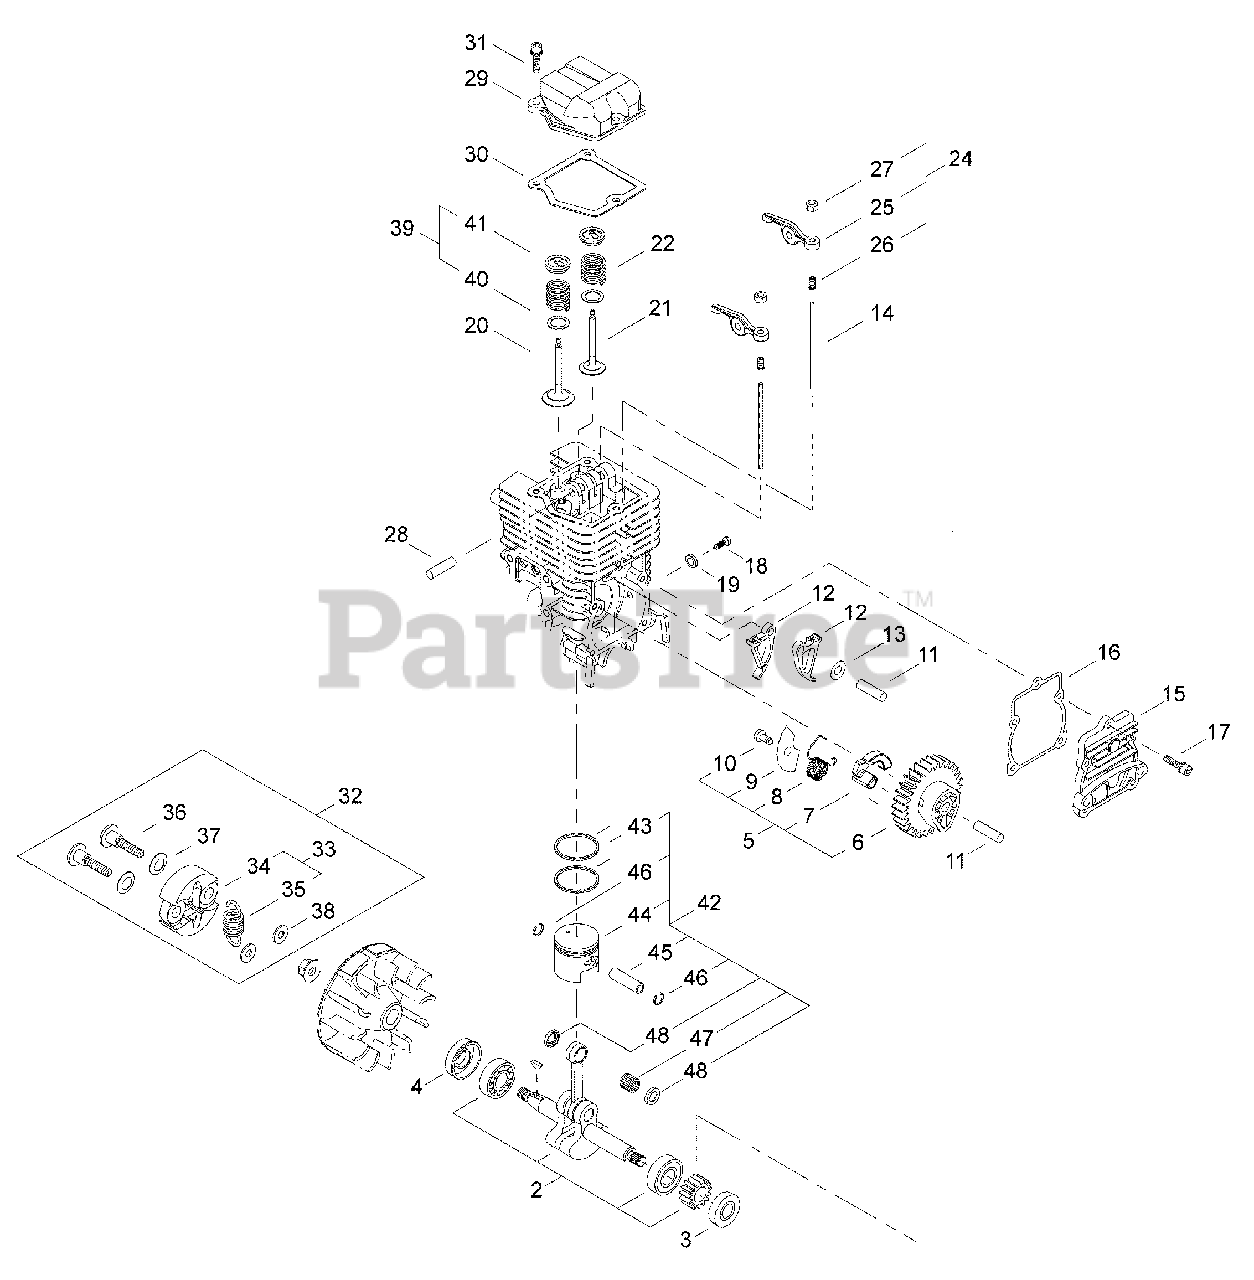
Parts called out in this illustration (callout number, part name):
2	CRANKSHAFT ASSY
3	SEAL, OIL - 12
4	SEAL, OIL - 12
5	CAM GEAR ASSY
6	GEAR, CAM
7	WEIGHT
8	SPRING
9	COVER, PLATE
10	SCREW - 4X6 -- TAPPING
11	PIN - LOCATING
12	FOLLOWER, CAM
13	WASHER - 5
14	PUSHROD
15	COVER, CAM GEAR
16	GASKET
17	SCREW - 4X14
18	SCREW - 5
19	WASHER
20	VALVE, INTAKE
21	VALVE, EXHAUST
22	SPRING, VALVE
24	ROCKER ARM ASSY
25	ARM, ROCKER
26	SCREW, ADJUST
27	LOCKNUT, ADJUSTER
28	SHAFT, ROCKER ARM - 5X31.8
29	COVER, ROCKER ARM
30	GASKET
31	SCREW - 4X12
32	CLUTCH SHOE SET
33	CLUTCH ASSY
34	SHOE, CLUTCH
35	SPRING, CLUTCH
36	BOLT, CLUTCH
37	WASHER - SPRING
38	WASHER - 6
39	VALVE RETAINER ASSY
40	WASHER, VALVE - 9
41	RETAINER, VALVE
42	PISTON KIT
43	RING, PISTON
44	PISTON
45	PIN, PISTON
46	RING, RETAINING
47	BEARING, NEEDLE
48	SPACER - 9
